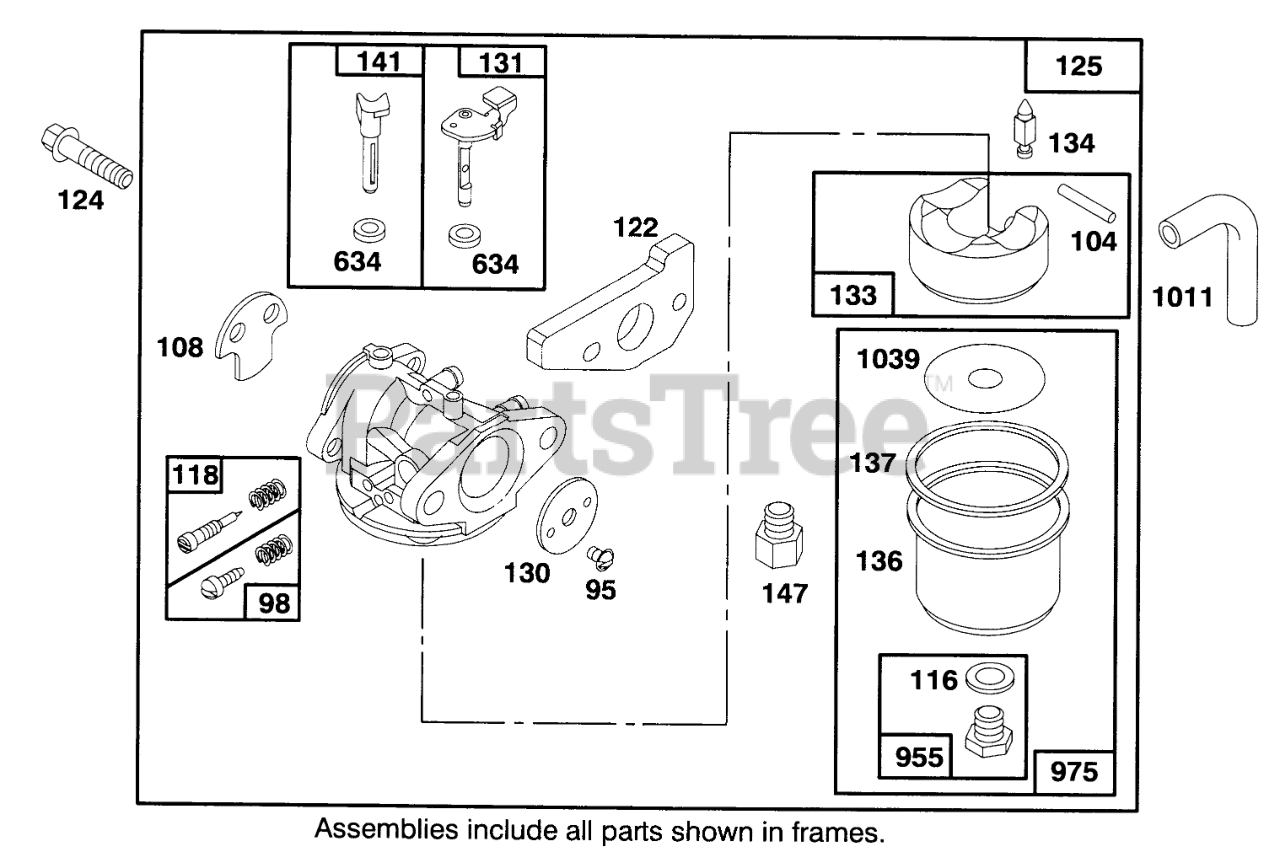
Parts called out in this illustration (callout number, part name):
95	SCREW - ROUND HEAD
98	IDLE ADJUSTING SCREW
104	FLOAT HINGE PIN
108	CHOKE VALVE
116	SEALING GASKET
118	VALVE KIT - NEEDLE
122	ADAPTER ASSEMBLY
124	HEX HEAD SCREW
125	CARBURETOR ASSEMBLY
130	THROTTLE VALVE
131	THROTTLE SHAFT
133	FLOAT-CARBURETOR
134	Valve-Inlet (Includes Seat)
136	FLOAT BOWL
137	FLOAT BOWL GASKET
141	CHOKE SHAFT
147	JET ADAPTER
634	SEAL WASHER
955	HEX HEAD SCREW
975	CARBURETOR BOWL ASM
1011	VENT TUBE
1039	FLOAT LIMITER
